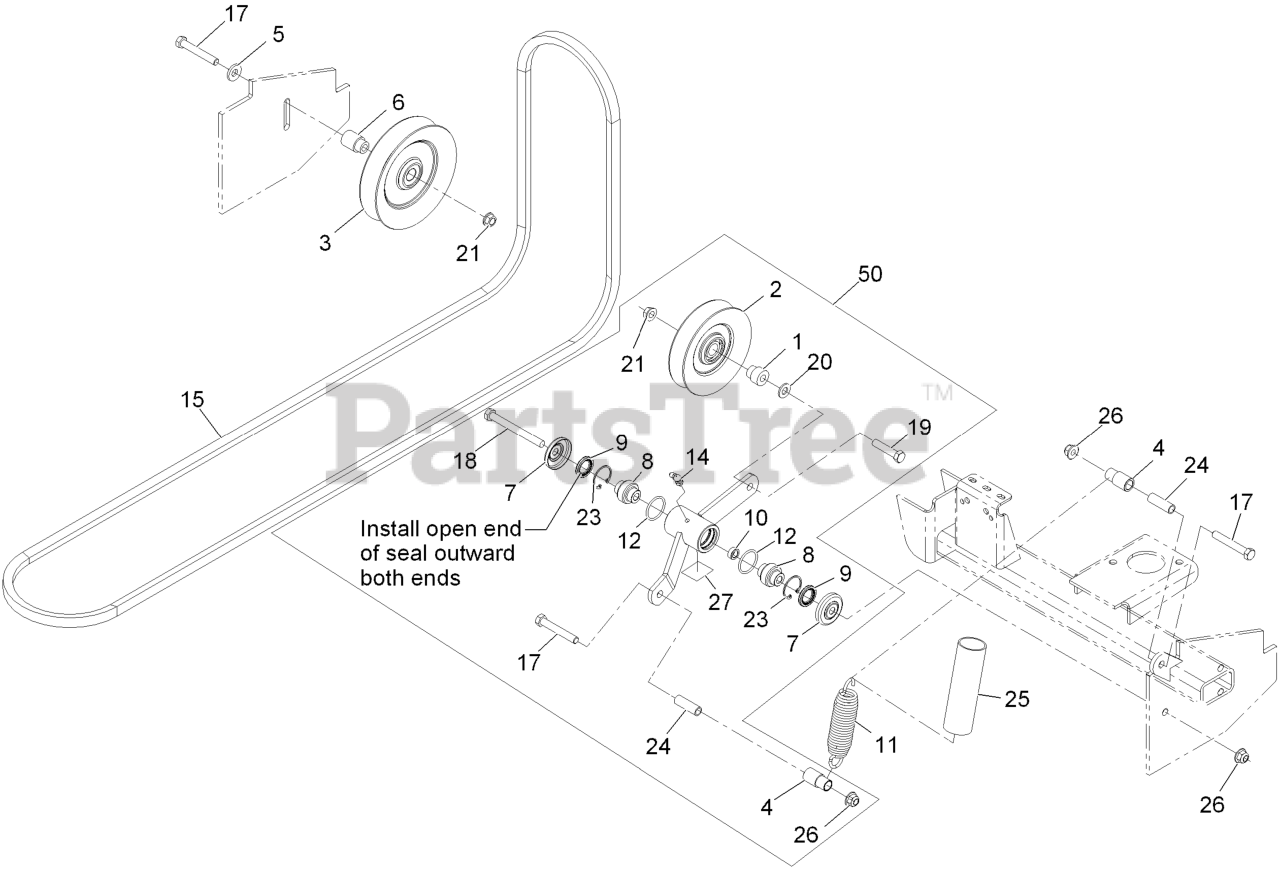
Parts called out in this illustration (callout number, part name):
1	BUSHING-IDLER
2	PULLEY-IDLER
3	PULLEY-IDLER
4	BUSHING,PLASTIC
5	WASHER-BELLEVILLE
6	BUSHING-IDLER
7	GUARD-TOP
8	BEARING-SPHERICAL
9	SEAL-LIP, SINGLE
11	KIT, SPRING-DAMPENER
14	FITTING-GREASE, 90 DEG
15	BELT,B 123.2
17	BOLT-CARR
18	SCREW-HH
19	SCREW-HH
20	WASHER-FLAT
21	Nut-Nyloc 3/8-16 Flg
23	RING-SNAP
25	DAMPENER,SPRING
26	NUT-HF, NI
27	DECAL,GREASE
50	IDLER ARM W/SHEAVE ASM
